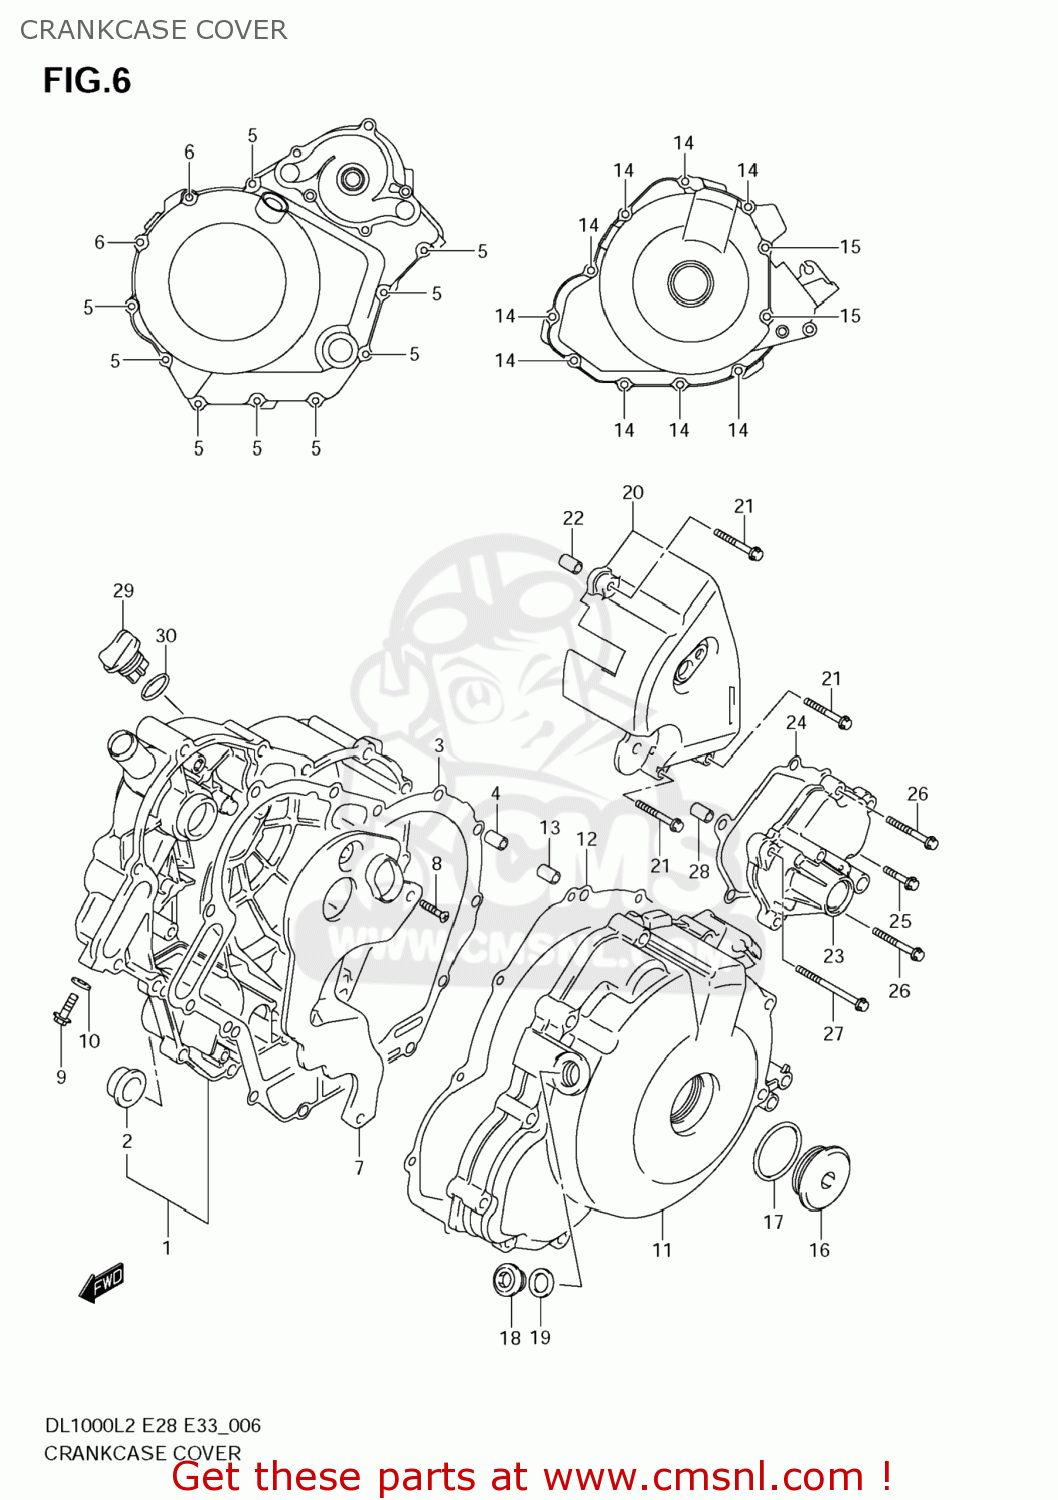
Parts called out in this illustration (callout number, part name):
1	COVER COMP,CLU
2	LENS,OIL LEVEL CHECK
3	GASKET,CLUTCH COVER (NAS)
4	PIN
5	BOLT(6X30)
6	BOLT(6X75)
7	SEPARATOR,OIL
8	SCREW
9	BOLT
10	GASKET(6.4X11.5X0.8) (NAS)
11	COVER,MAGNETO
12	GASKET,MAGNETO COVER (NAS)
13	PIN
14	BOLT(6X35)
15	BOLT(6X70)
16	PLUG(SILVER)
17	O RING(D:3.1,ID:32.7)
18	PLUG,14X12
19	GASKET(13.8X18.8X4.8) (NAS)
20	COVER,ENGINE SPROCKET
21	BOLT(6X35)
22	PIN
23	COVER,GEAR SHIFT
24	GASKET,GEAR SHIFT COVER (NAS)
25	BOLT(6X105)
26	BOLT
27	BOLT
28	PIN
29	PLUG,ENGINE OIL FILLER
30	O RING(D:3.1,ID:16.8)
